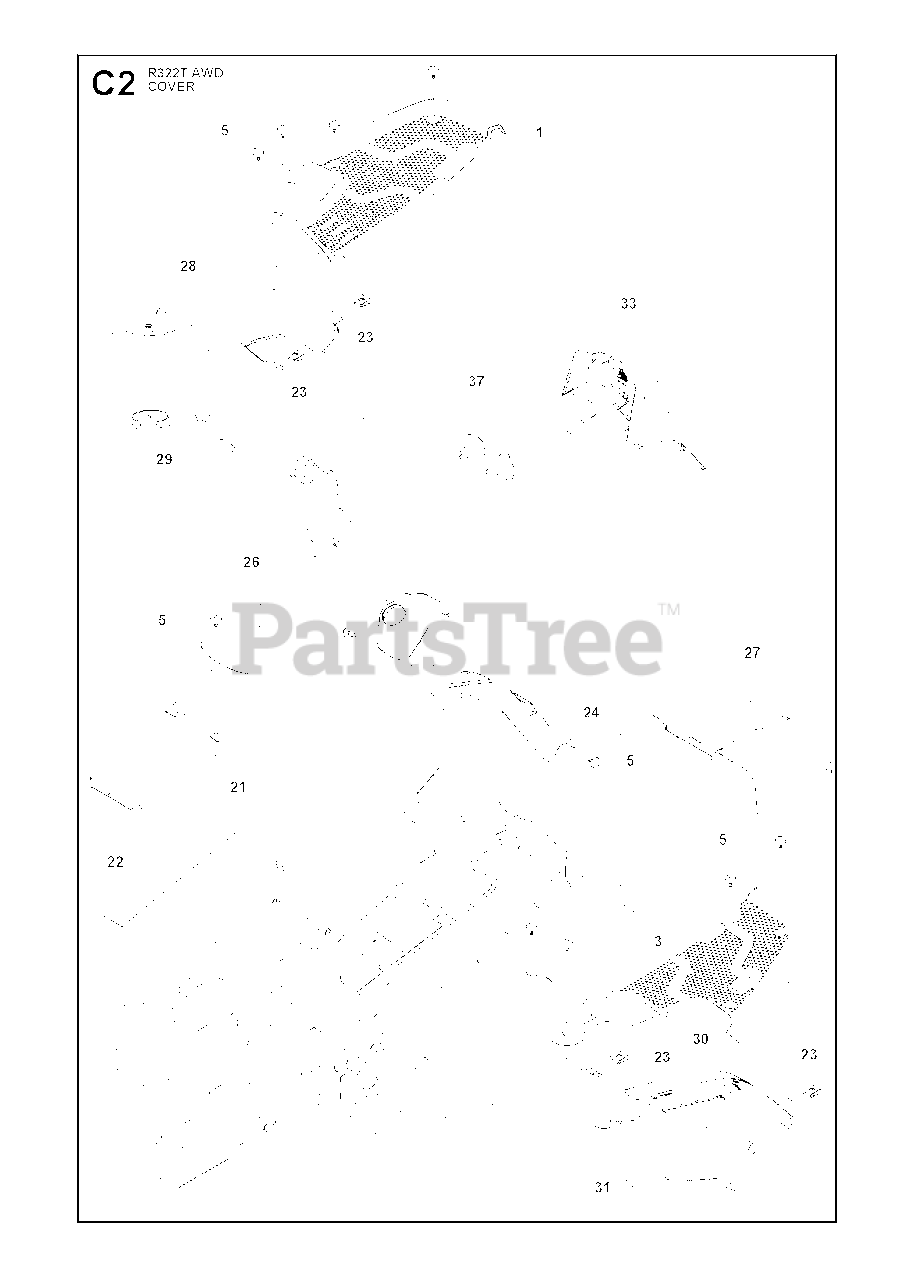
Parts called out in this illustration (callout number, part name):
1	FOOT PLATE
3	FOOT PLATE
26	PROTECTIVE COVER
27	UNIT COVER
29	LOCKING NUT
31	CONTROL COVER
33	COVER
